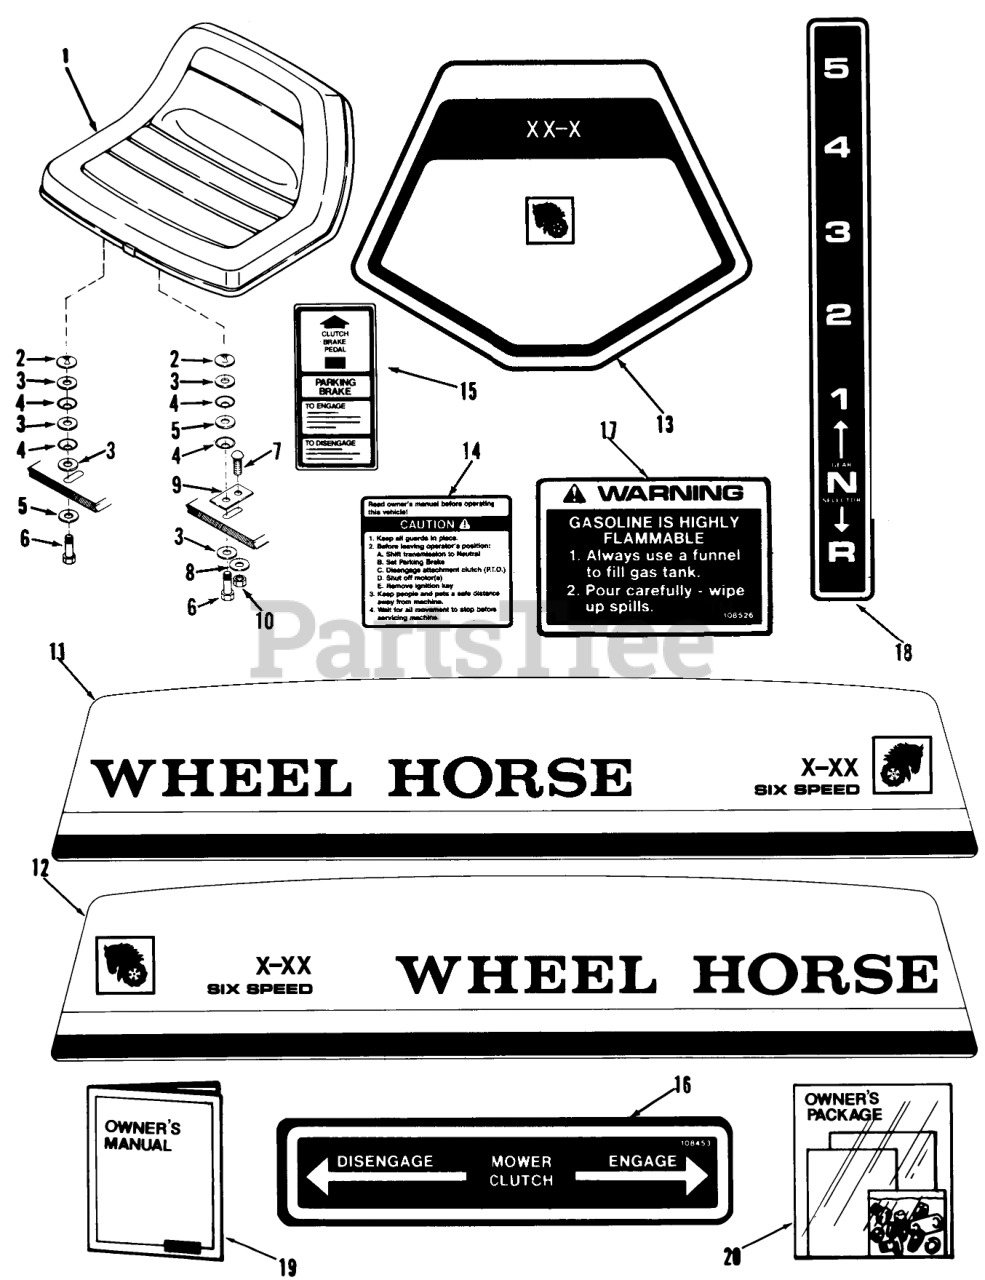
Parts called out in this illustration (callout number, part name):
4	WASHER-SPRING
5	WASHER 5/16 SAE
7	CARRIAGE BOLT -4
19	Owner-s Manual
20	New Rider Loose Parts Pkg A-81E
20	New Rider Loose Parts Pkg A-111
20	New Rider Loose Parts Pkg A-51
20	New Rider Loose Parts Pkg A-81R
